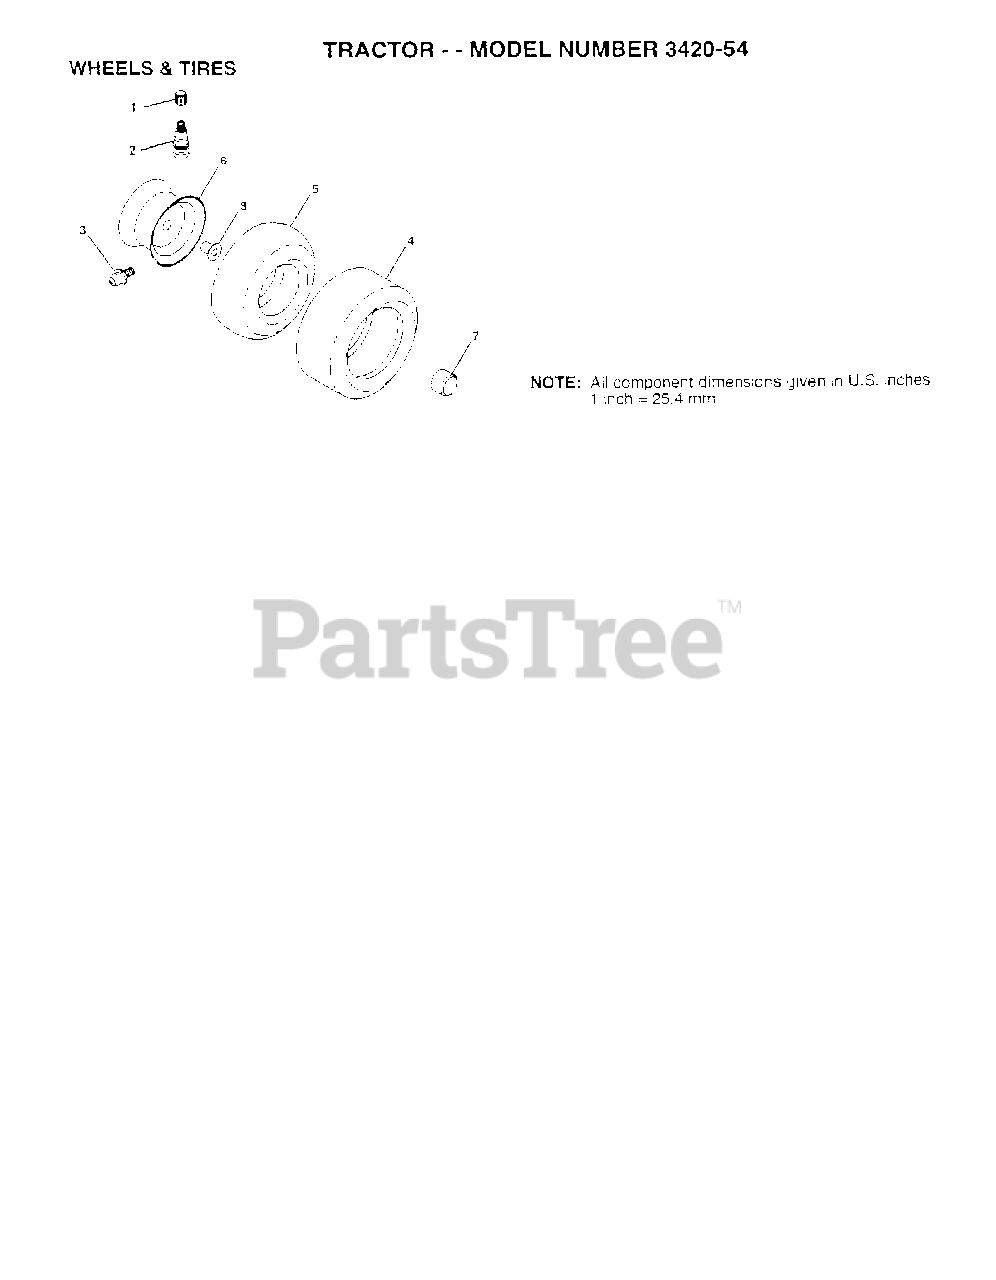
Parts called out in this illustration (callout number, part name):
1	VALVE CAP
2	VALVE STEM LT
3	FITTING LT
4	TIRE HEAVY DUTY
4A	TIRE 20X8-8 TURF SAVER
5	TUBE.5.3/4.5/6
5A	TUBE - UNIVERSAL FOR 8" RIM
6	RIM.ASM.6".FRONT.SILVER
6A	RIM 8" SILVER
7	CAP.HUB.FRONT.LT.BLACK
8	BEARING T
